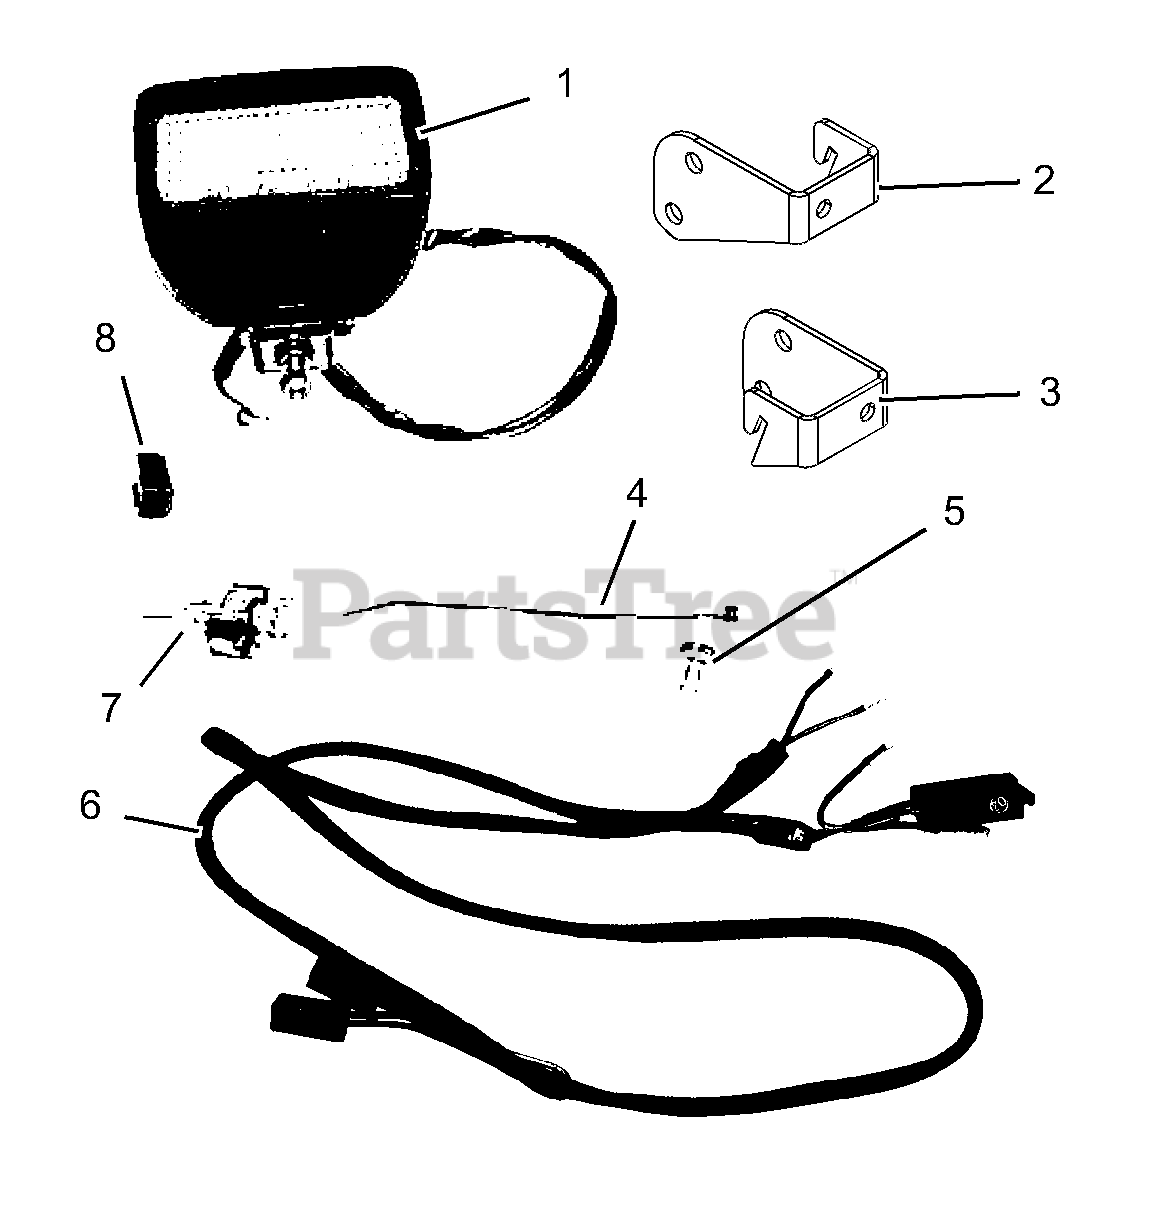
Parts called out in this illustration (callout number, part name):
1	Headlight
2	Right Hand Bracket
3	Left Hand Bracket
4	Cable Tie
5	3/8" x 1/2" Self-Tapping Screw
6	Headlight Wire Harness
7	Headlight Switch
